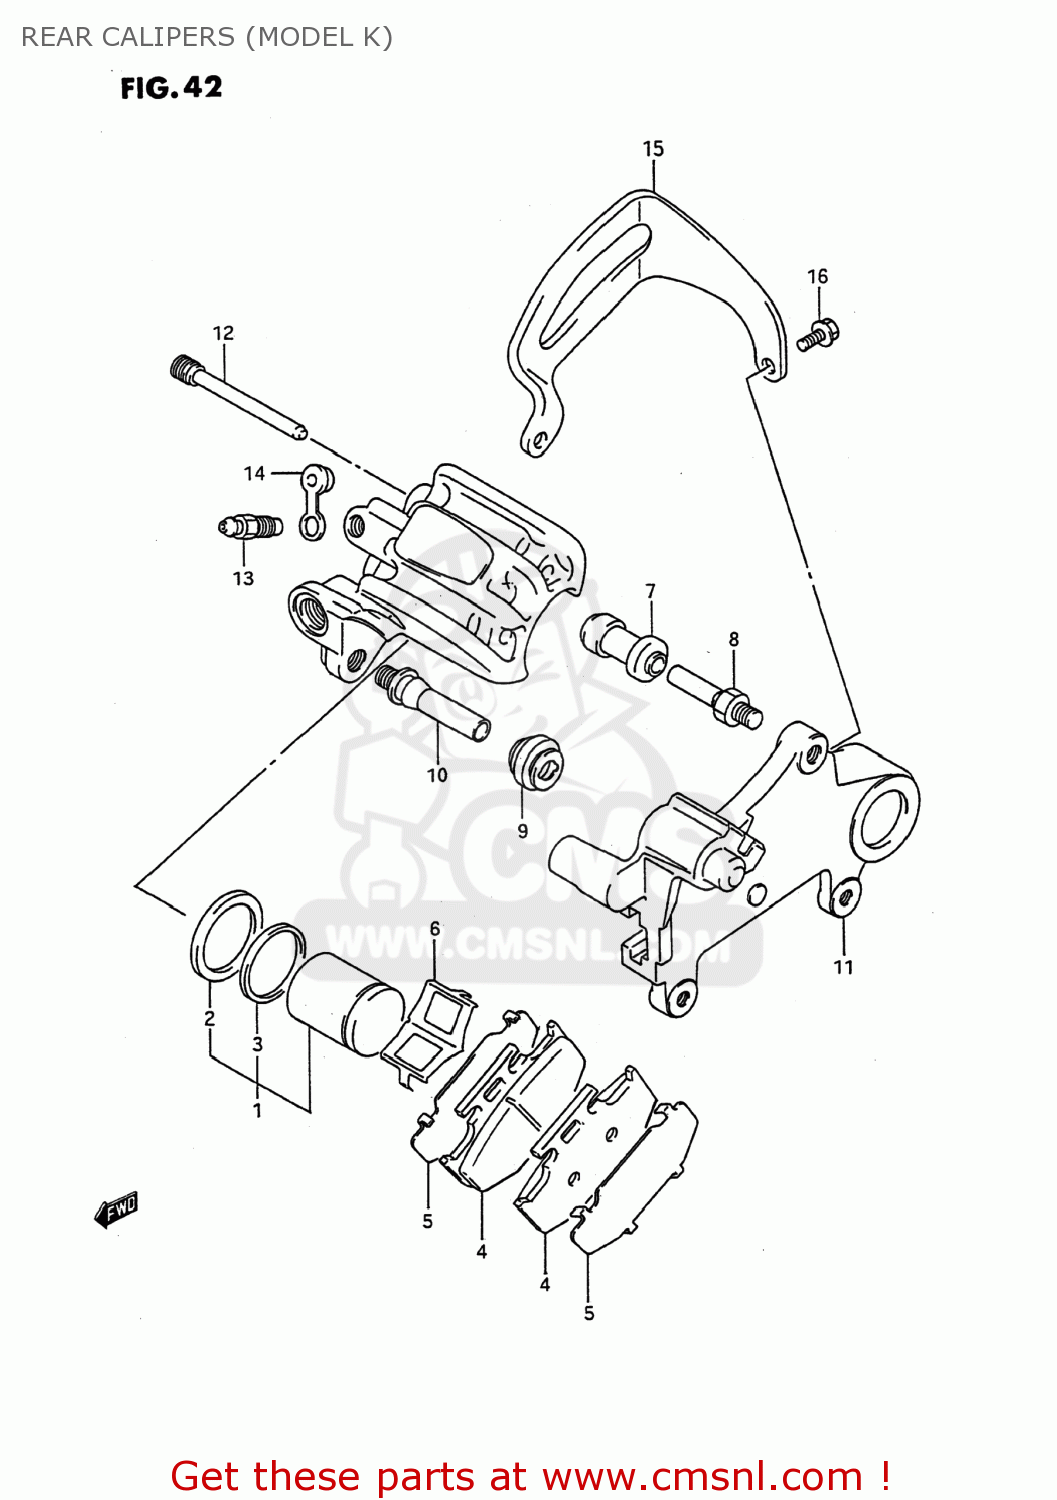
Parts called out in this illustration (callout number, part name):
1	PISTON SET
2	SEAL,PISTON
3	SEAL,DUST
4	PAD
5	SHIM
6	SPRING
7	BOOT
8	PIN,BOLT
9	BOOT
10	PIN
11	BRACKET
12	PIN,HANGER
13	BLEEDER
14	CAP,BLEEDER
15	GUARD,REAR CALIPER
16	BOLT
